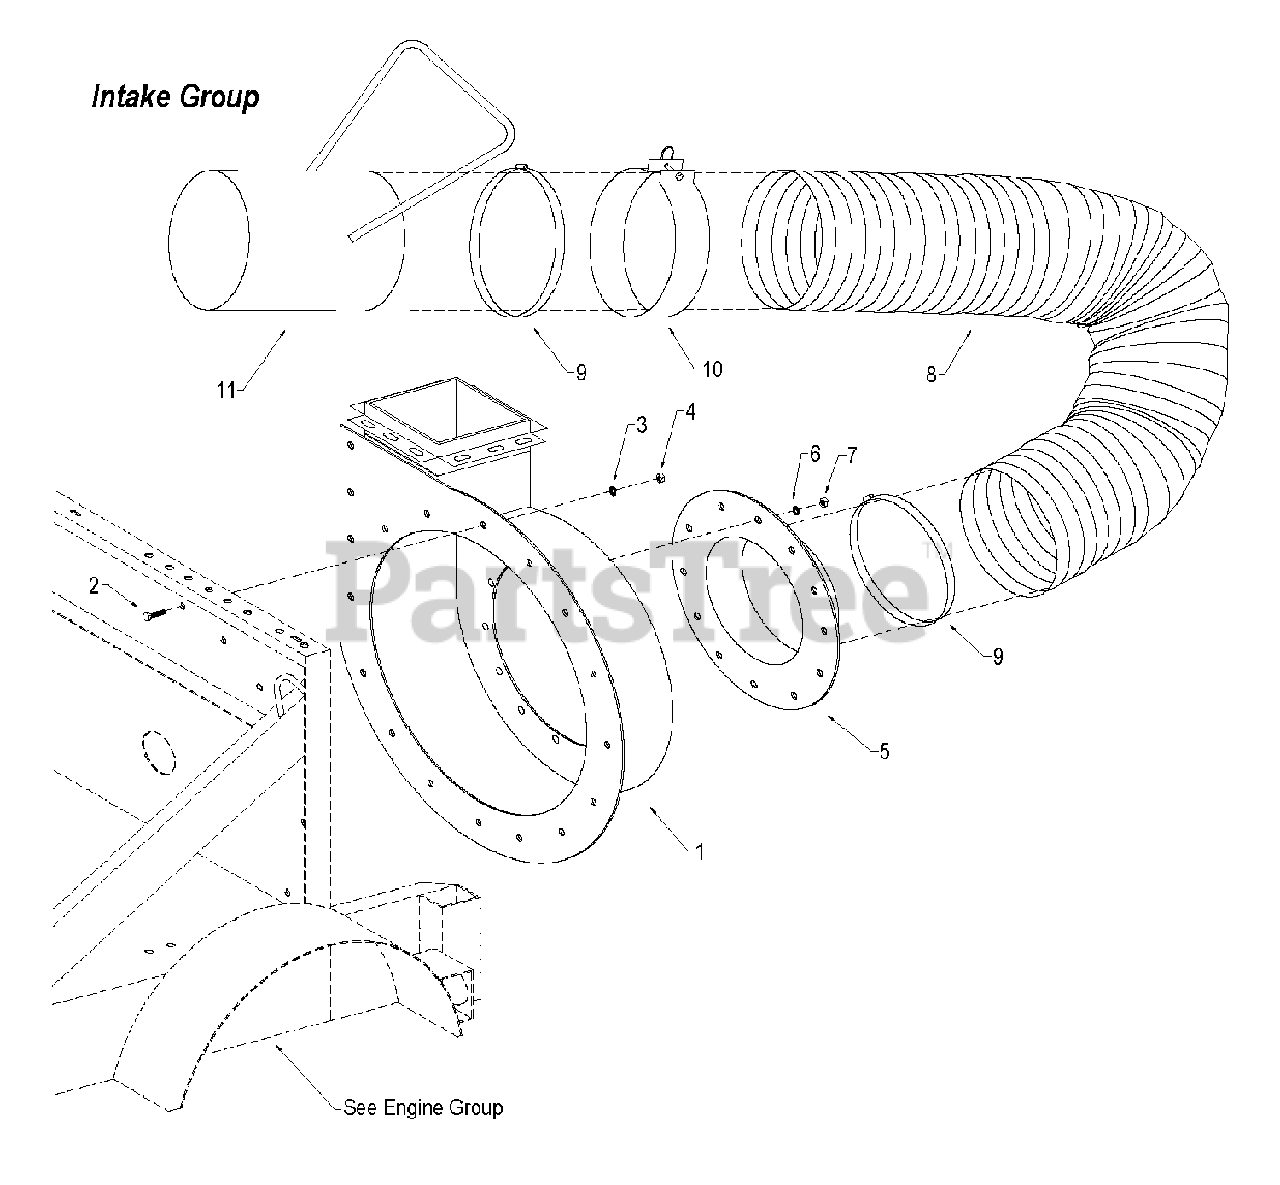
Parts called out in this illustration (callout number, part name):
1	Housing, impeller – complete with liner kit below
2	Bolt, hex - 3/8-16 x 1"
3	Washer, lock - 3/8"
4	Nut, hex - 3/8-16
5	Flange, intake, 16 straight (skid version)
5	Flange, intake, 16 90 degree (CHW version)
6	Washer, lock - 1/2
7	Nut, hex - 1/2-13
8	Hose, intake - 16" x 7'
9	Clamp, hose - 16"
10	Band, hose support – 16 – with hardware *
11	Nozzle, intake - 16"
